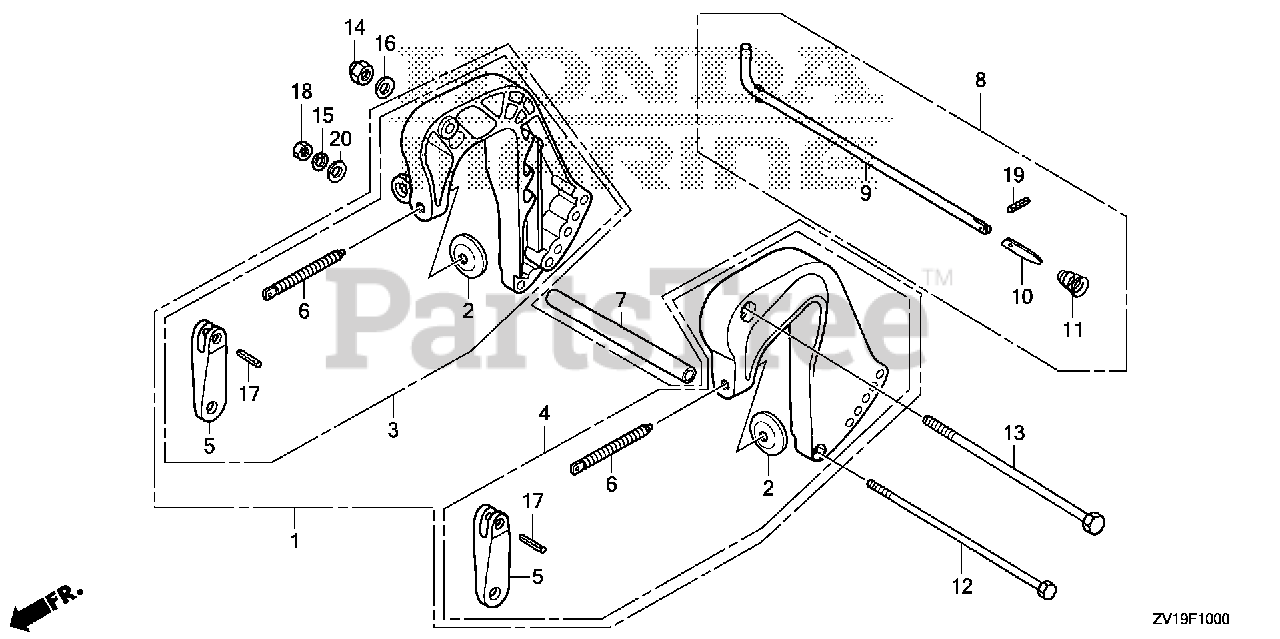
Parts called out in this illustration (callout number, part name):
1	BRACKET KIT, STERN *NHB14M* (AQUA MARINE SILVER METALLIC)
2	PLATE, PUSH
3	BRACKET, R. STERN *NHB14M* (AQUA MARINE SILVER METALLIC)
4	BRACKET, L. STERN *NHB14M* (AQUA MARINE SILVER METALLIC)
5	GRIP, CLAMP
6	SCREW, CLAMP
7	COLLAR, DISTANCE (6MM)
8	ROD, ADJUSTING
9	ROD, ADJUSTING
10	STOPPER, ROD
11	SPRING, ROD ADJUSTING
12	BOLT, HEX. (6X140)
13	BOLT, HEX. (8X130)
14	NUT, SELF-LOCK (8MM)
15	WASHER, SPRING (6MM)
16	WASHER (8MM)
17	RIVET (4X22.6)
18	NUT, HEX. (6MM)
19	PIN, SPRING (2X6)
20	WASHER, PLAIN (6MM) Use from Frame SN 4800713.
